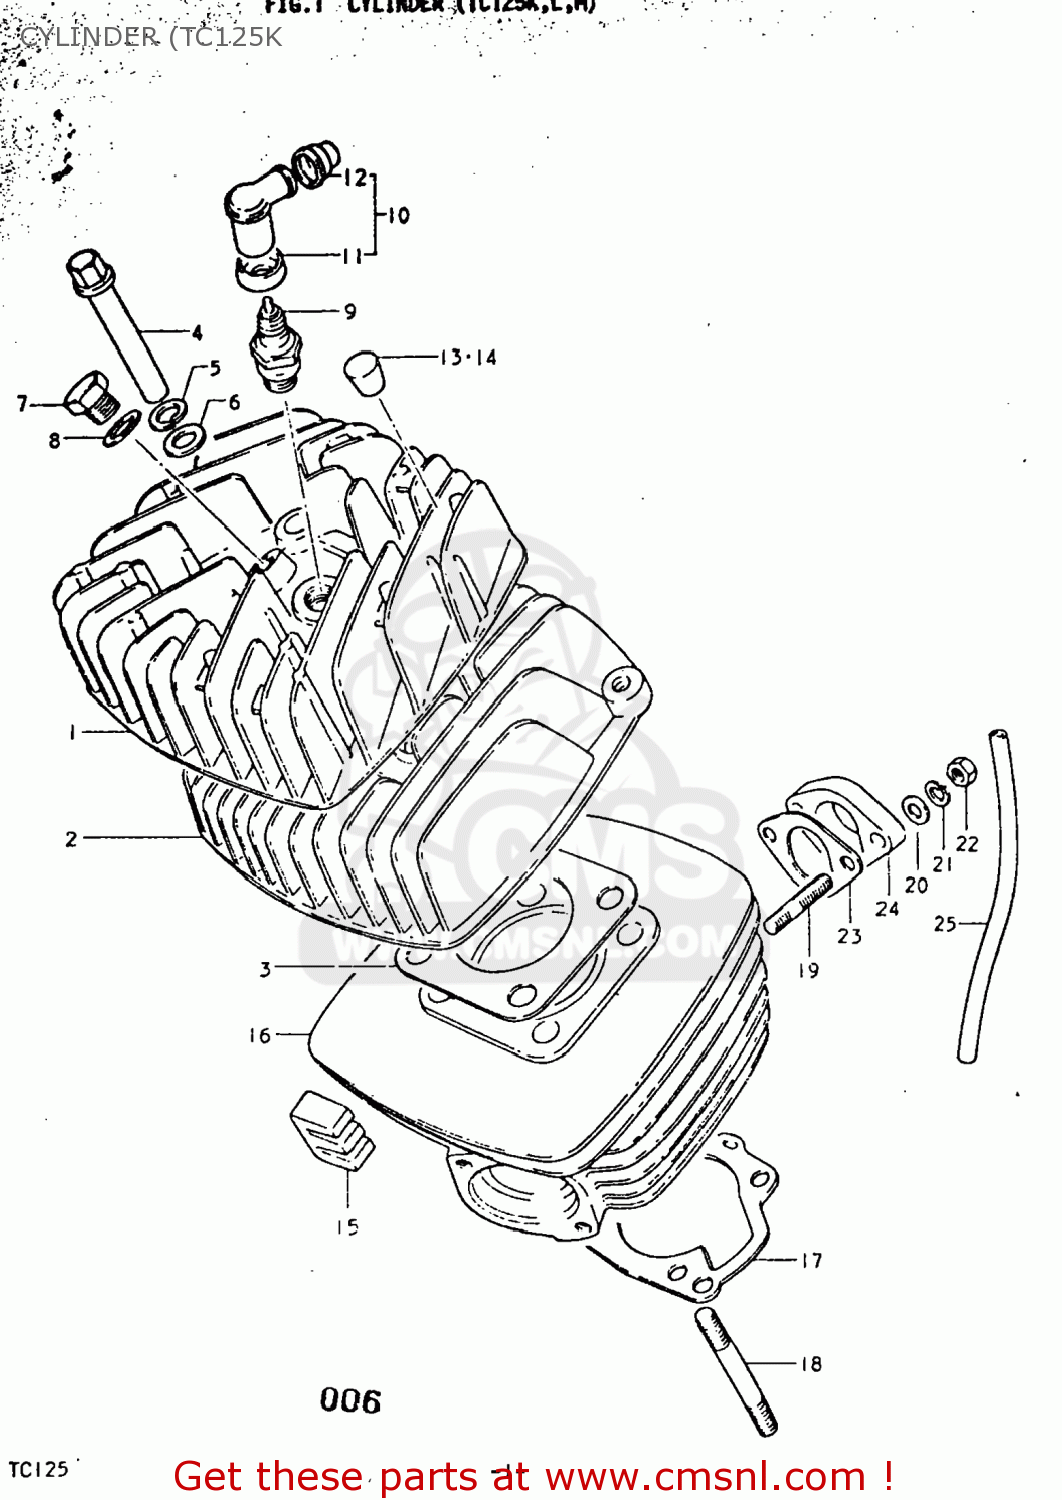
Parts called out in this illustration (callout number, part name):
1	HEAD,CYLINDER
2	HEAD,CYLINDER
3	GASKET,CYLINDER HEAD (NAS)
4	NUT
5	WASHER,LOCK 12
6	WASHER
7	PLUG
8	GASKET(14X19.2X2) (NAS)
9	SPARK PLUG
10	CAP,SPARK PLUG
11	SEAL,SPARK PLUG
12	SEAL,SPARK PLU
13	PAD,CYLINDER HEAD
14	PAD,CYLINDER HEAD
15	PAD,CYLINDER
16	CYLINDER
17	GASKET,CYLINDER (MCA)
18	STUD 8X65
19	STUD BOLT
20	WASHER
21	LOCK WASHER
22	NUT
23	GASKET,CARBURETOR (MCA)
24	INSULATOR,CARBURETOR
25	HOSE
